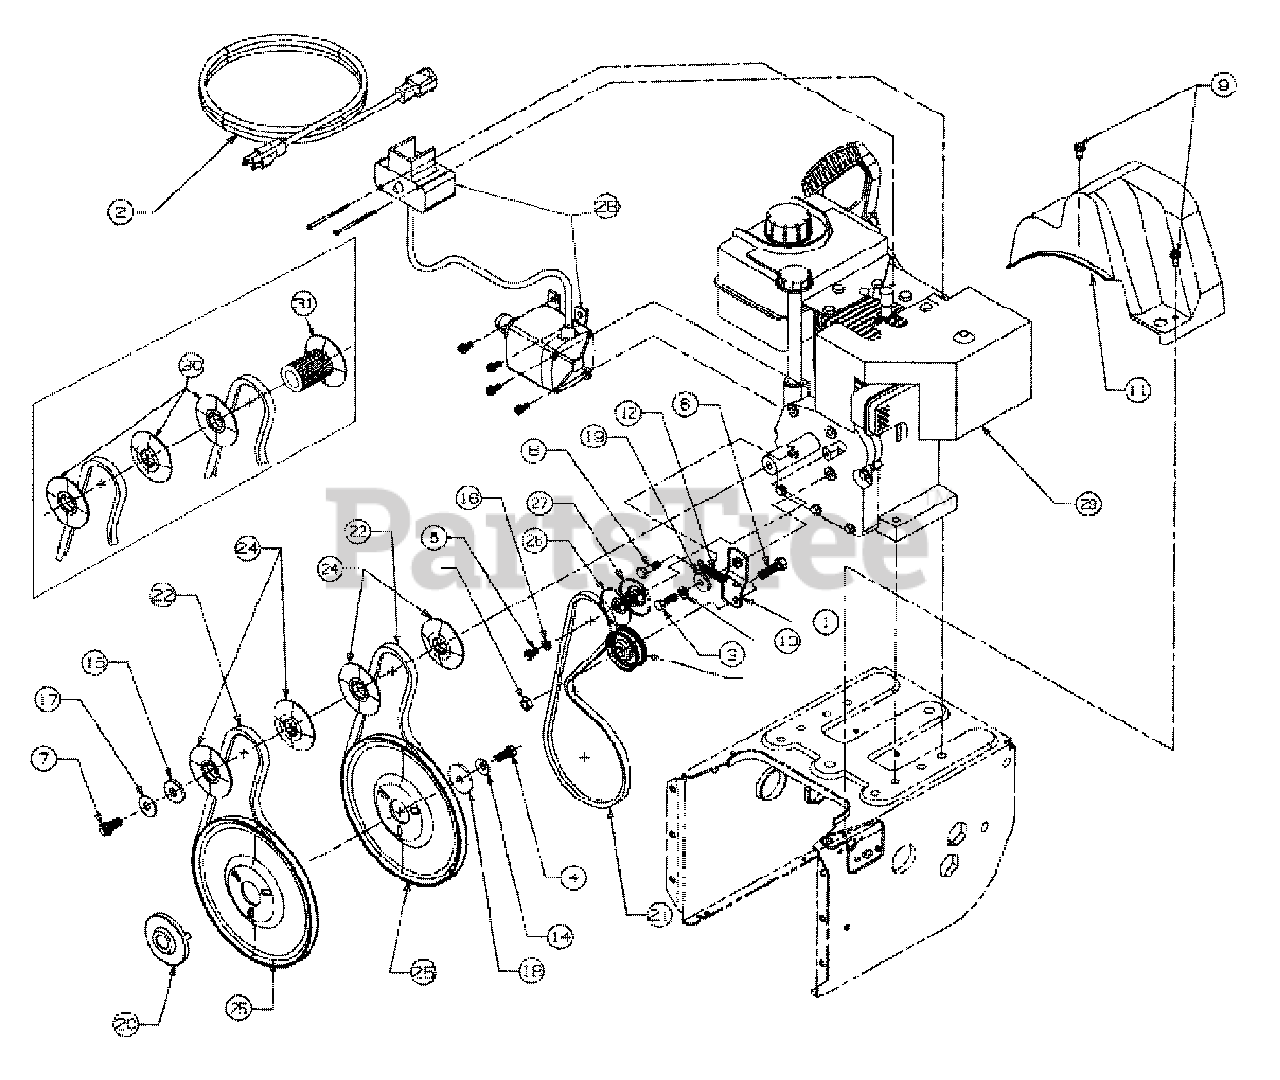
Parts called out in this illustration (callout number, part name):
3	Screw
6	Screw
12	Spring
13	Washer-Lock
16	Washer-Lock
19	Shoulder Spacer
20	Pulley Adapter
21	V-Belt
22	V-Belt
24	Pulley, Half (753F)
25	Pulley Auger
26	Pulley, Half
27	Pulley, Half
28	Starter (753F)
29	Engine
30	Pulley, Half (733E)
31	Pulley, Half (733E)
